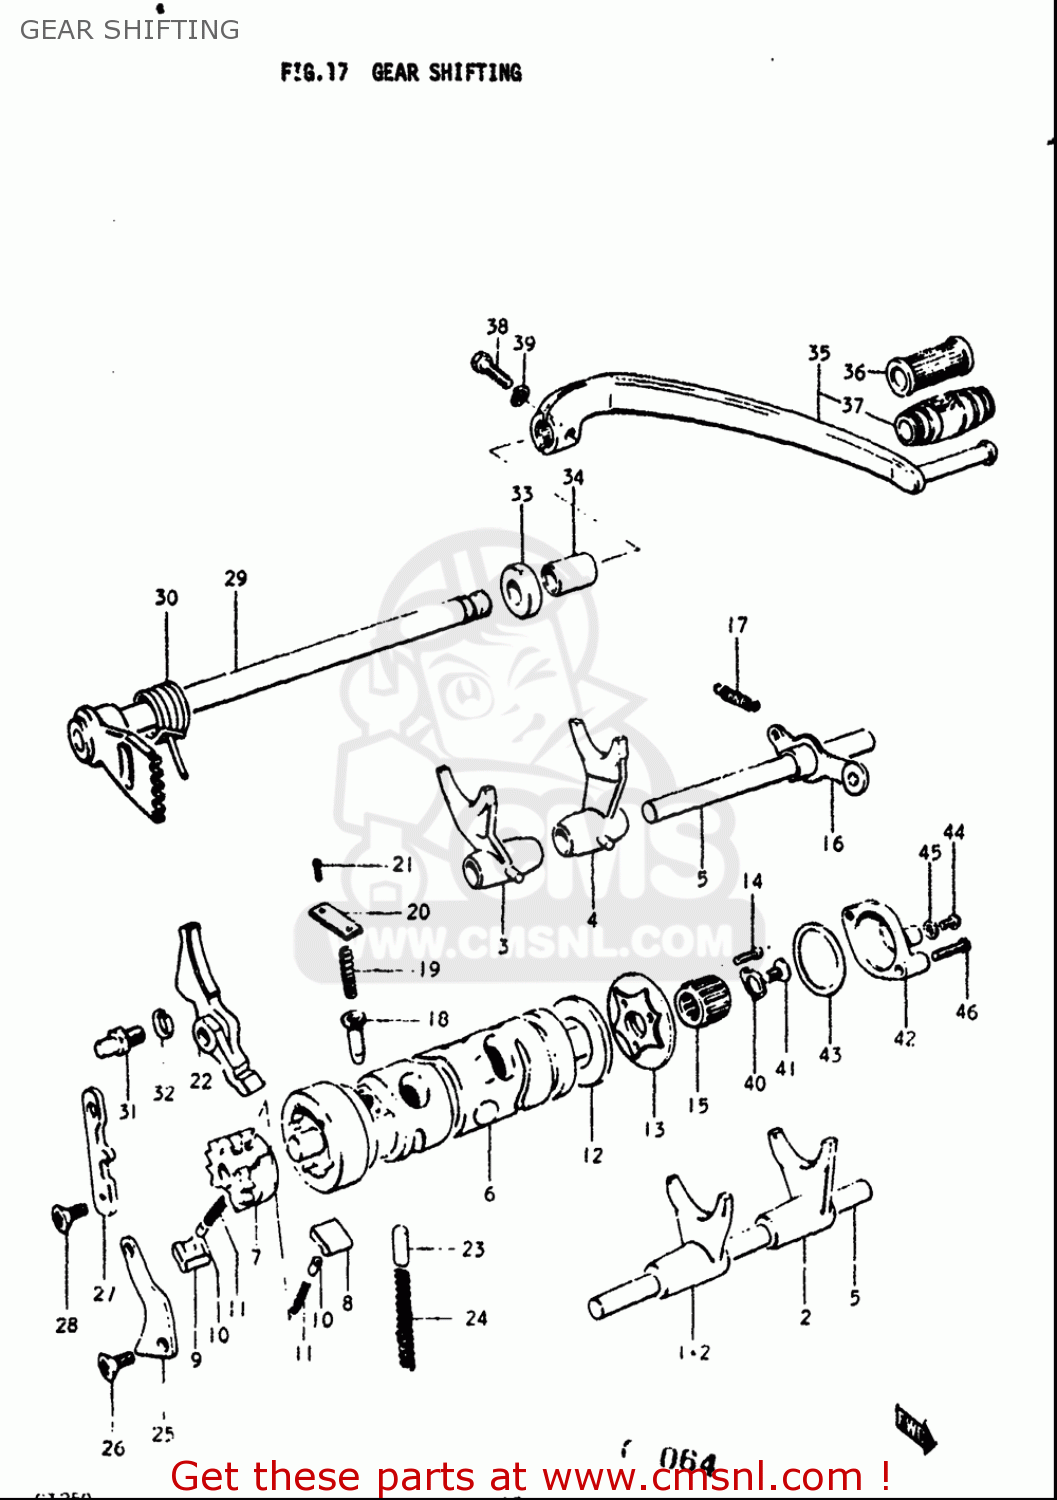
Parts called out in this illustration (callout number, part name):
7	GEAR,GEAR SHIFT CAM DRIVEN
8	PAWL,GEAR SHIFT NO.1
9	PAWL,GEAR SHIFT NO.2
10	PIN(5X8)
11	SPRING
12	WASHER(40X45X1)
14	SCREW
15	BEARING(16X22X12)
17	SPRING
19	SPRING
21	SCREW
25	LIFTER,GEAR SHIFT PAWL
26	SCREW
27	GUIDE,GEAR SHIFT CAM
28	SCREW
30	SPRING
31	STOPPER,GEAR SHIFT ARM
32	WASHER,LOCK
33	SEAL,OIL (12X22X9)
34	CUSHION
35	LEVER ASSEMBLY,GEAR SHIFTING
36	RUBBER,GEAR SHIFT PEDAL
37	RUBBER,GEAR SHIFT PEDAL
38	BOLT
39	WASHER,LOCK
40	CONTACT,GEAR SHIFT SWITCH
41	SCREW
42	BODY,GEAR SHIFT SWITCH
43	O RING(D:1.9,ID:27.7)
44	SCREW
45	WASHER
46	SCREW
